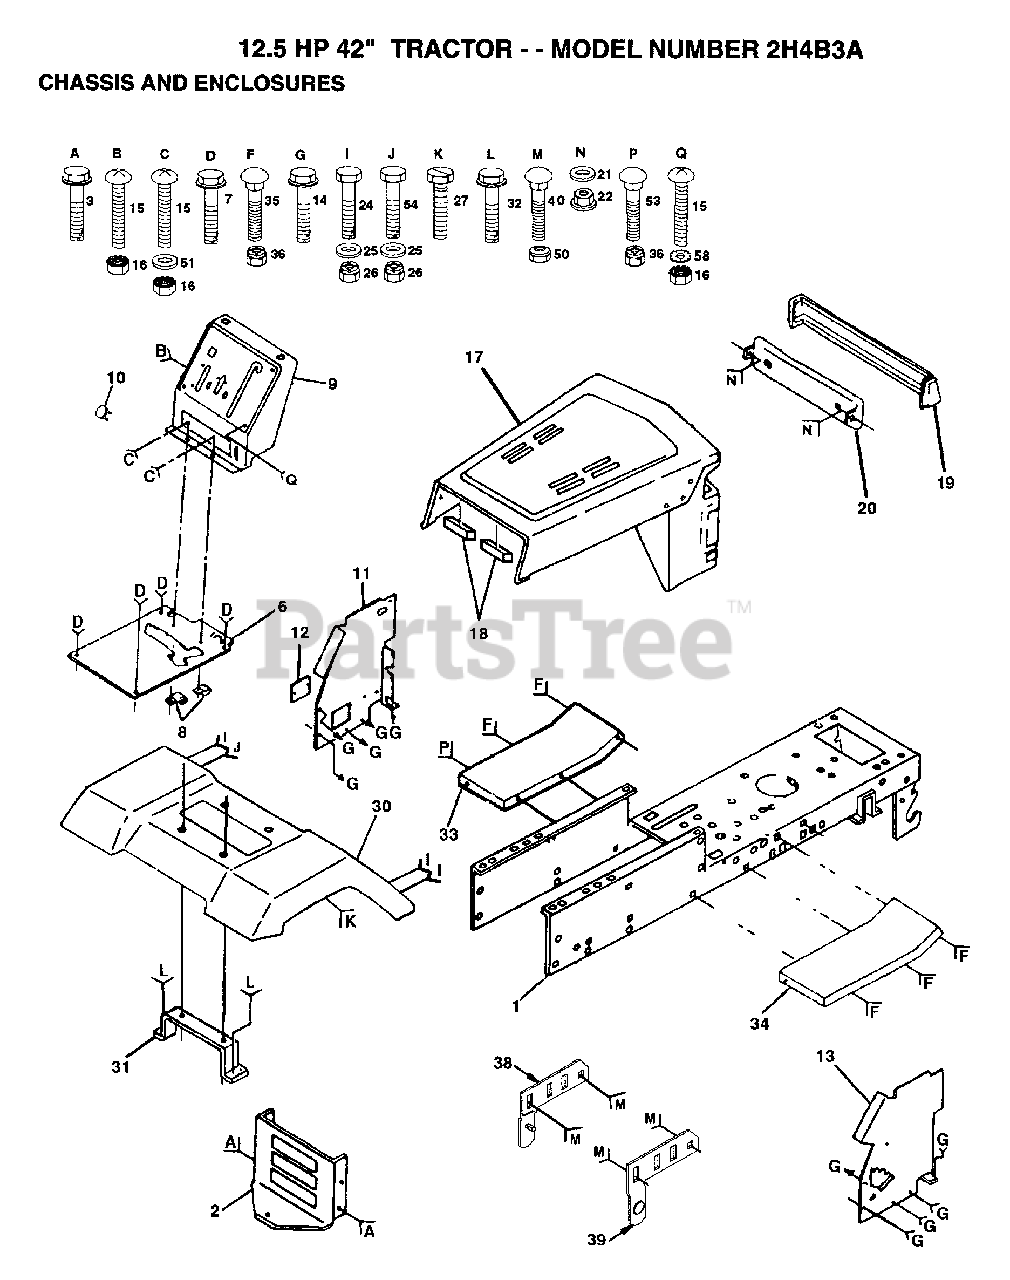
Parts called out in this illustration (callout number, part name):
3	SCREW
7	SCREW LT
8	CLIP T
10	PLUG BUTTON T
11	PANEL DASH LH
12	COVER ACCESS
14	SCREW LT
15	SCREW
17	HOOD/GRILL ASM
19	LENS SERVICE KIT
21	WASHER PM
22	PAL NUT LT
25	WASHER
27	SCREW LT
30	FENDER
31	BRKT FENDER
32	SCREW
33	FOOTREST LH
34	FOOTREST RH
35	BOLT
38	PIVOT BRKT LH
39	PIVOT BRKT RH
50	NUT
51	WASHER
58	LOCKWASHER
